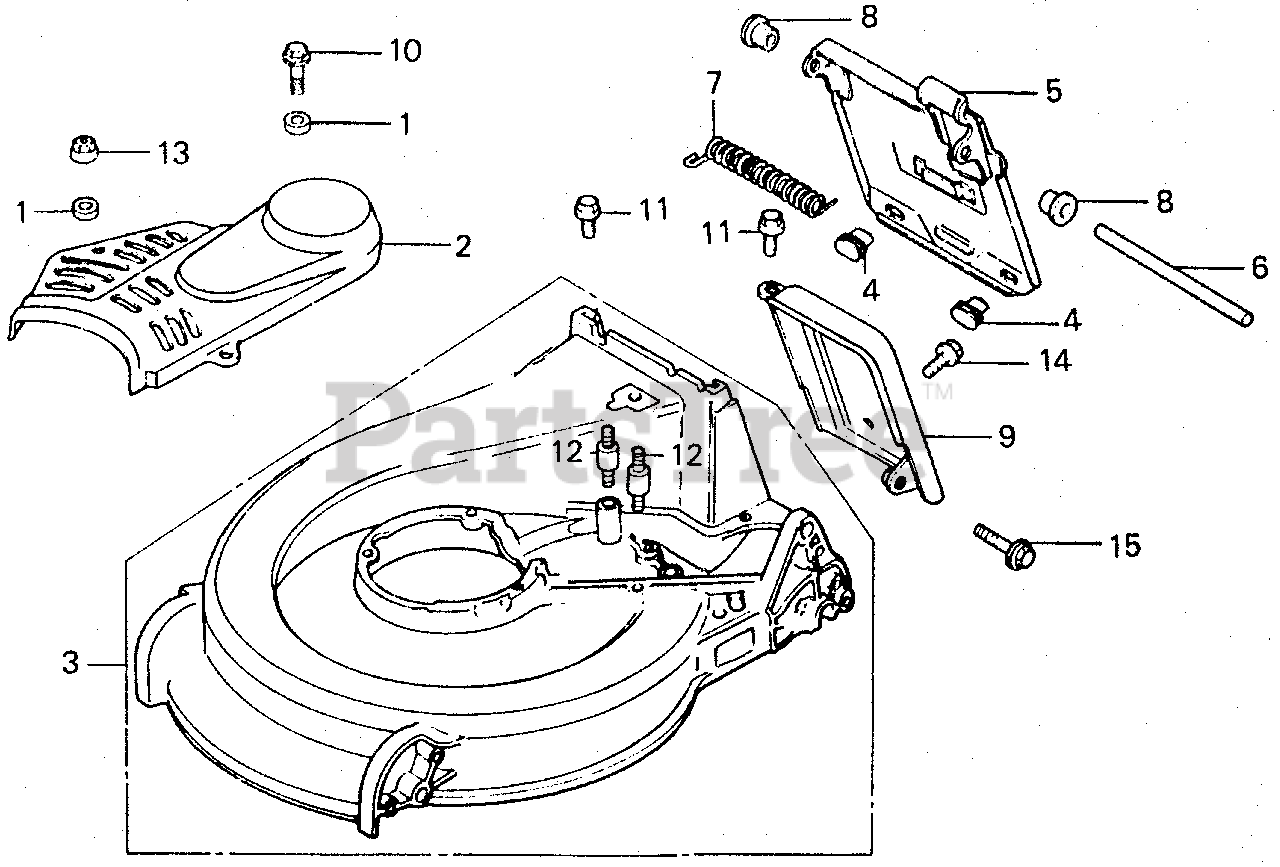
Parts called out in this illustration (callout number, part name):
1	COLLAR, FAN
2	COVER, BELT
3	HOUSING, CUTTER *NH2M* (METALLIC SILVER)
4	STOPPER, DISCHARGE GUARD Use up to Frame SN 1186736.
5	GUARD, DISCHARGE
6	SHAFT, DISCHARGE GUARD (NOT AVAILABLE)
7	SPRING, GUARD RETURN (NOT AVAILABLE)
8	BUSH, DISCHARGE GUARD
9	PANEL, BAG OPEN *NH2M* (METALLIC SILVER)
10	BOLT, FLANGE (6X14)
11	BOLT, FLANGE (6X20) (CT200)
12	BOLT, STUD (6X28) (CT200)
13	NUT, FLANGE (6MM)
14	BOLT, FLANGE (6X12) Use up to Engine SN 1543277.
15	BOLT, FLANGE (6X25)
